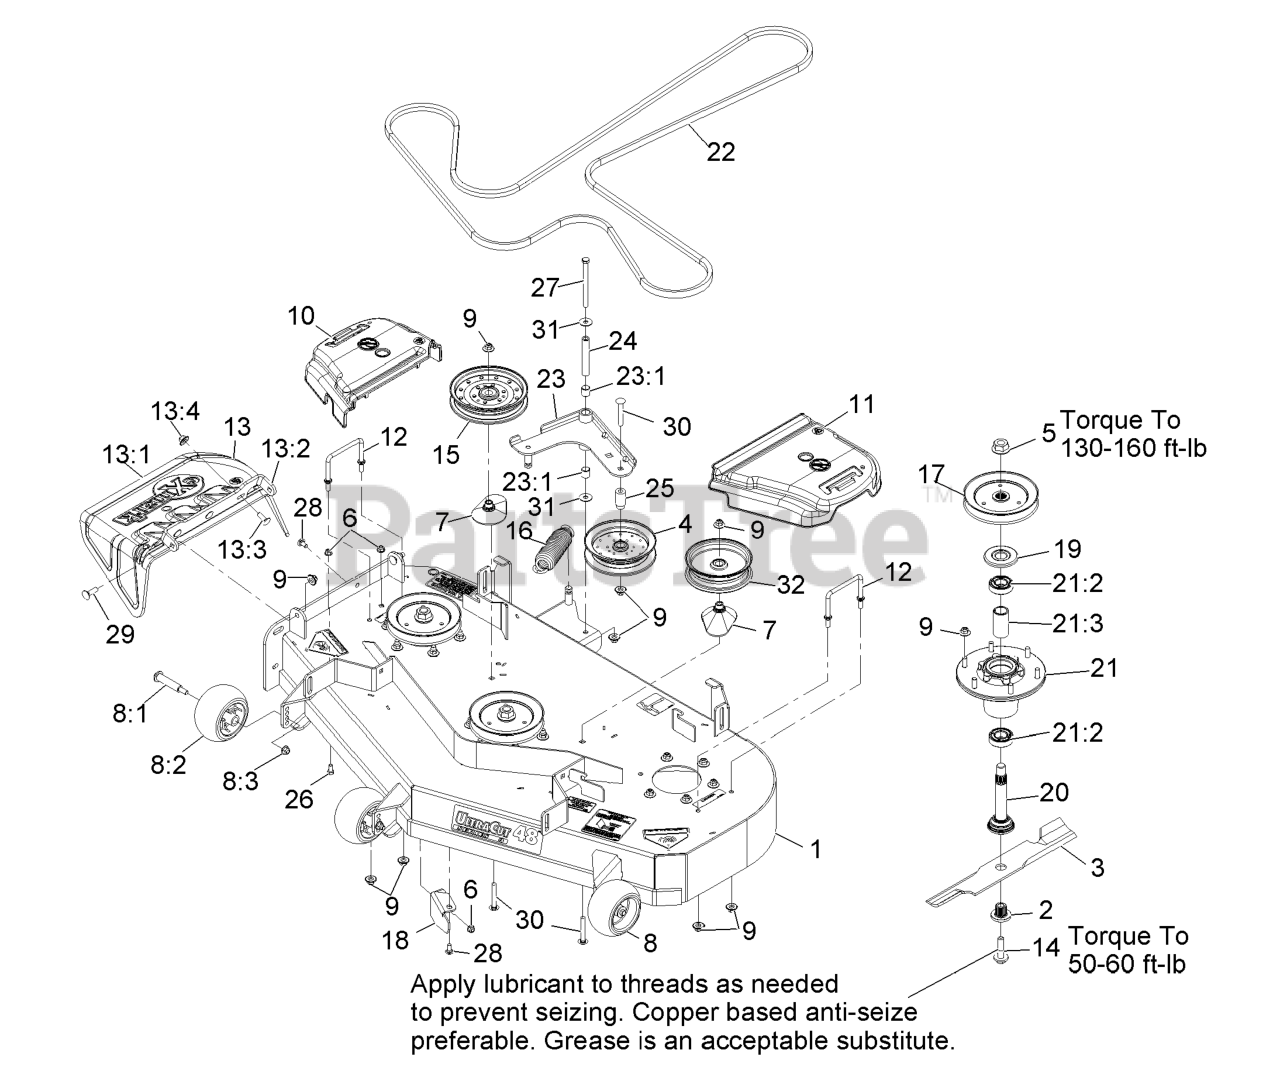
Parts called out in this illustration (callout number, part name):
1	ASM-DECK W/DECALS 48
2	BUSHING,SPLINED
5	NUT-FLANGE
6	NUT-HF, NI
7	SPACER-PULLEY
8	ANTI-SCALP ROLLER KIT
8:1	BOLT-SHOULDER
8:2	ROLLER-SCALP, ANTI
8:3	NUT-HF, NI
9	Nut-Nyloc 3/8-16 Flg
10	COVER-BELT, RH
11	COVER-BELT, LH
12	WIREFORM-COVER
13	ASM,DISCHARGE CHUTE
13:1	CHUTE,DISCHARGE
13:2	BRACKET,DISCHARGE CHUTE
13:3	SCREW-CARR
13:4	Nut-Nyloc 3/8-16 Flg
14	SCREW,SEMS 1/2-20 X 2.19
17	SHEAVE,BLADE DRIVE 5.90
18	BAFFLE,DISCHARGE 483
19	GUARD,BEARING TOP .989
20	ASM-SPINDLE AND SEAL
21	ASM-CUTTER HSG WITH BEARINGS
21:2	BEARING-BALL
21:3	SPACER-BEARING
22	BELT-B154.88
23:1	SLEEVE-BEARING
24	BUSHING
25	BUSHING-IDLER
26	SCREW-HH
27	SCREW-HH
28	BOLT-CARR
29	BOLT-CARR
30	SCREW-CARR
